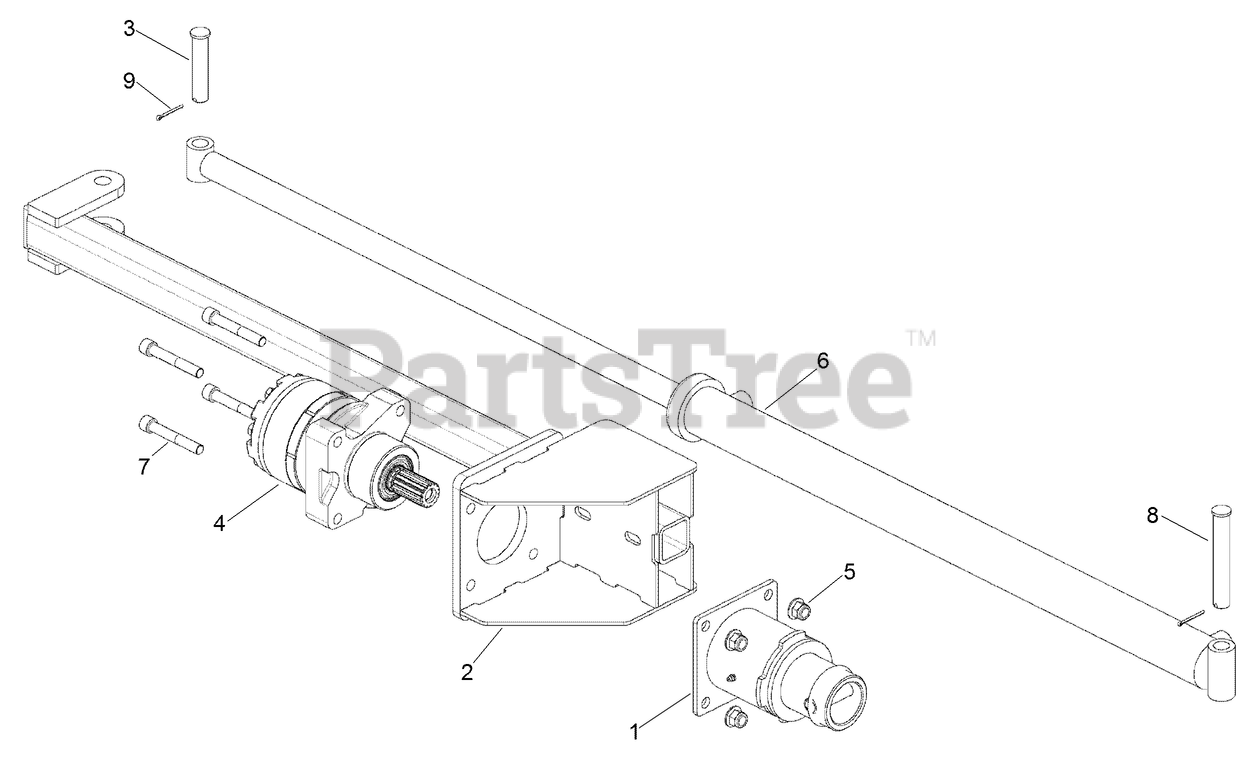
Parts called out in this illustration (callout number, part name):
1	STAKEDOWN COUPLER ASM
2	WELDMENT - Stake Down, DD1215
3	PIN - .75 x 3.5 Clevis
4	HYD MOTOR ASM
5	NUT-HHF, LOCK
6	HYD CYLINDER ASM
7	SCREW-HSH
8	PIN-CLEVIS
9	PIN-Cotter, 1/8 x 1-1/4 in ZN
